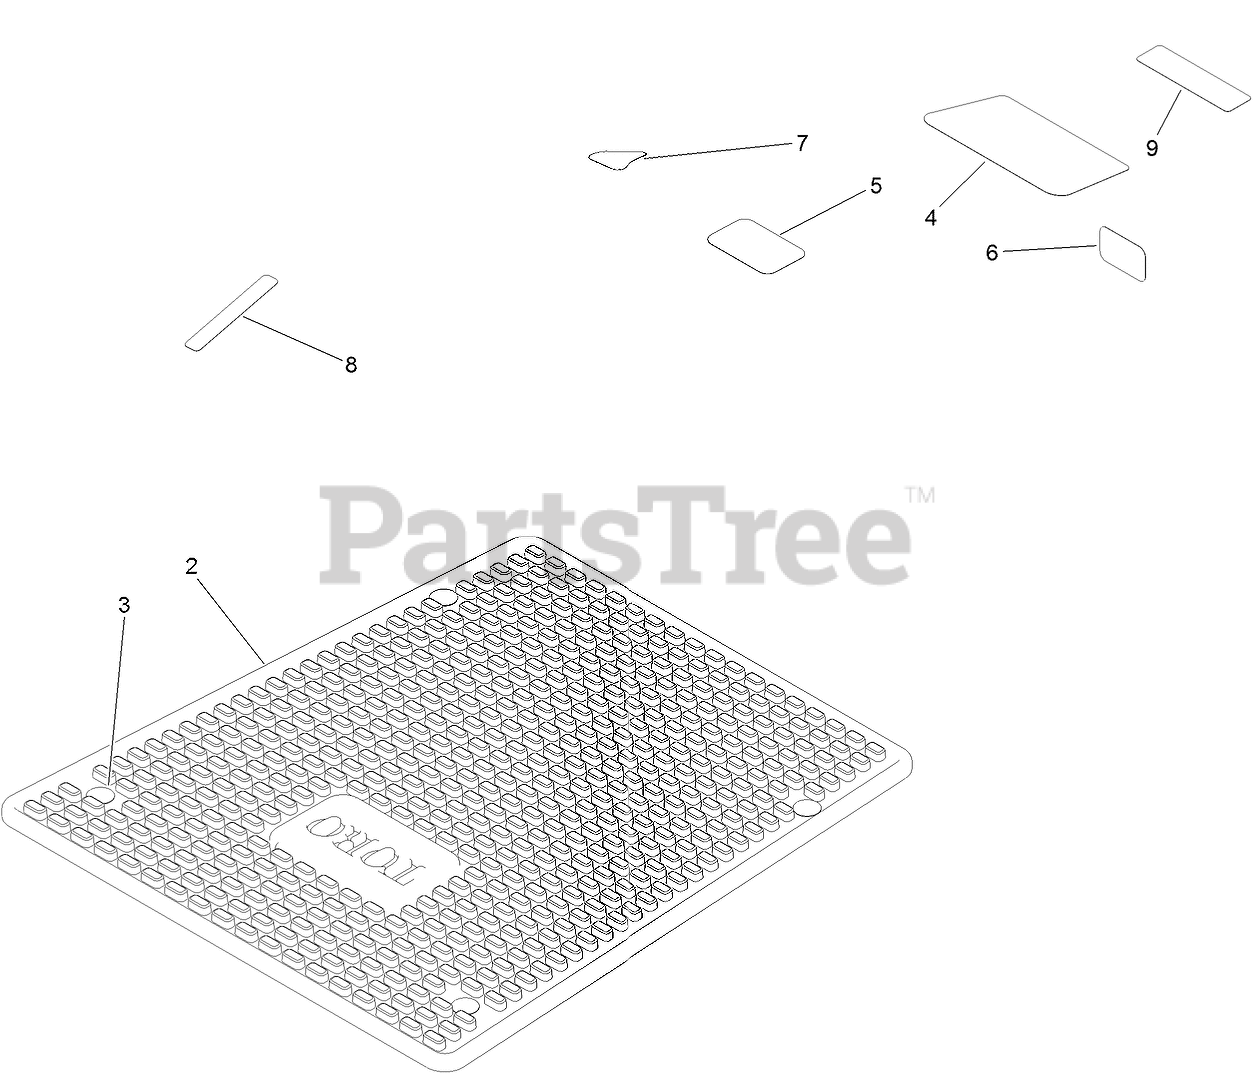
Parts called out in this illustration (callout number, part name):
2	MAT-FLOOR
3	PLUG-PLASTIC
4	DECAL-ENGINE
6	PLACARD-INTAKE
7	DECAL-DRAIN, OIL
8	DECAL-SHUTDOWN
9	DECAL-BUCKET
